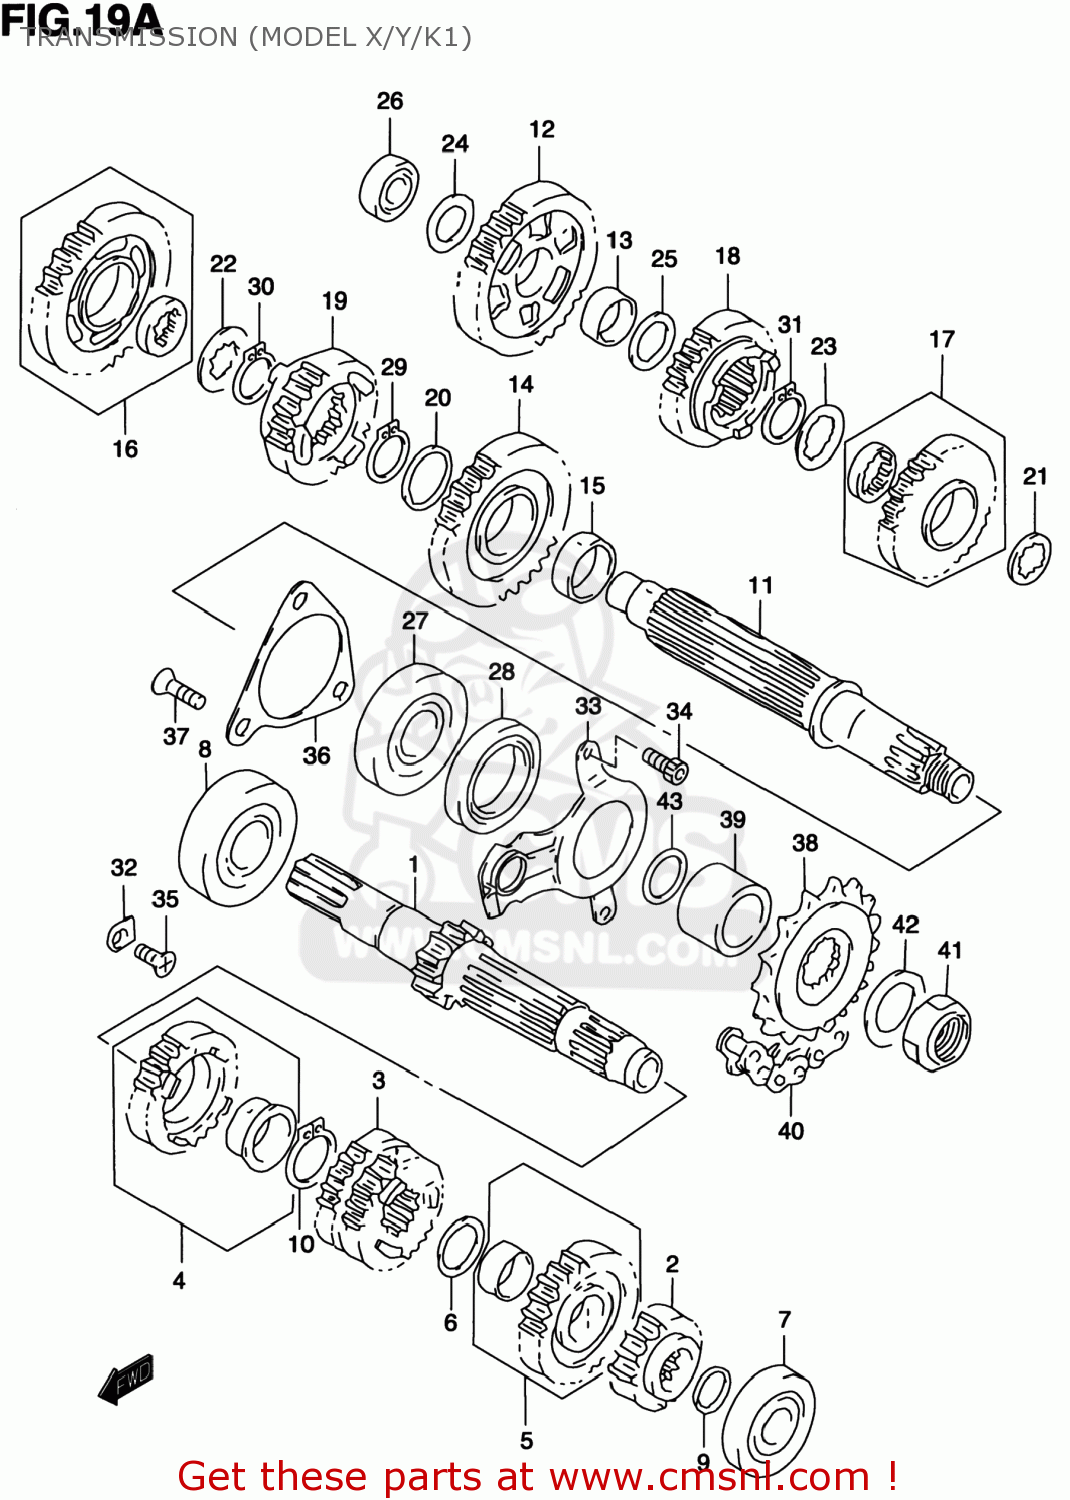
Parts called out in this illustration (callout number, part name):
1	SHAFT,COUNTER(NT:12)
2	GEAR,2ND DRIVE(NT:15)
3	GEAR,3RD & 4TH DRIVE(NT:18/27)
4	GEAR SET,FIFTH DRIVE (NT:
5	GEAR SET,SIXTH DRIVE (NT:
6	SHIM(22X30X1)
7	BEARING(20X47X14)
8	BEARING(25X62X17)
9	O RING(D:1.9,ID:16.6)
10	CIRCLIP
11	SHAFT,DRIVE
12	GEAR,1ST DRIVEN(NT:32)
13	BUSH
14	GEAR,2ND DRIVEN(NT:29)
15	BUSH,2ND DRIVEN GEAR
16	GEAR SET,THIRD DRIVEN (NT
17	GEAR SET,FOURTH DRIVEN (NT
18	GEAR,5TH DRIVEN(NT:25)
19	GEAR,SIXTH DRIVEN (NT:24)
20	WASHER(27X36X1)
21	WASHER,LOCK
22	WASHER,3RD & 4TH DRIVEN
23	WASHER,3RD & 4TH DRIVEN
24	SHIM(20X34X1)
25	SHIM(22X34X1)
26	BEARING(20X52X15)
27	BEARING(28X68X20)
28	SEAL,OIL(38X52X8)
29	CIRCLIP
30	CIRCLIP
31	CIRCLIP
32	RETAINER
33	RETAINER,DRIVESHAFT O
34	BOLT,STRANGER
35	SCREW
36	RETAINER,DRIVE SHAFT BEARING
37	SCREW(6X12)
38	SPROCKET,ENGINE(NT:17)
39	SPACER,ENGINE SPROCKET
40	CHAIN,DRIVE
41	NUT
42	SHIM(25X40X1.5)
43	O RING(D:2.4,ID:23.7)
